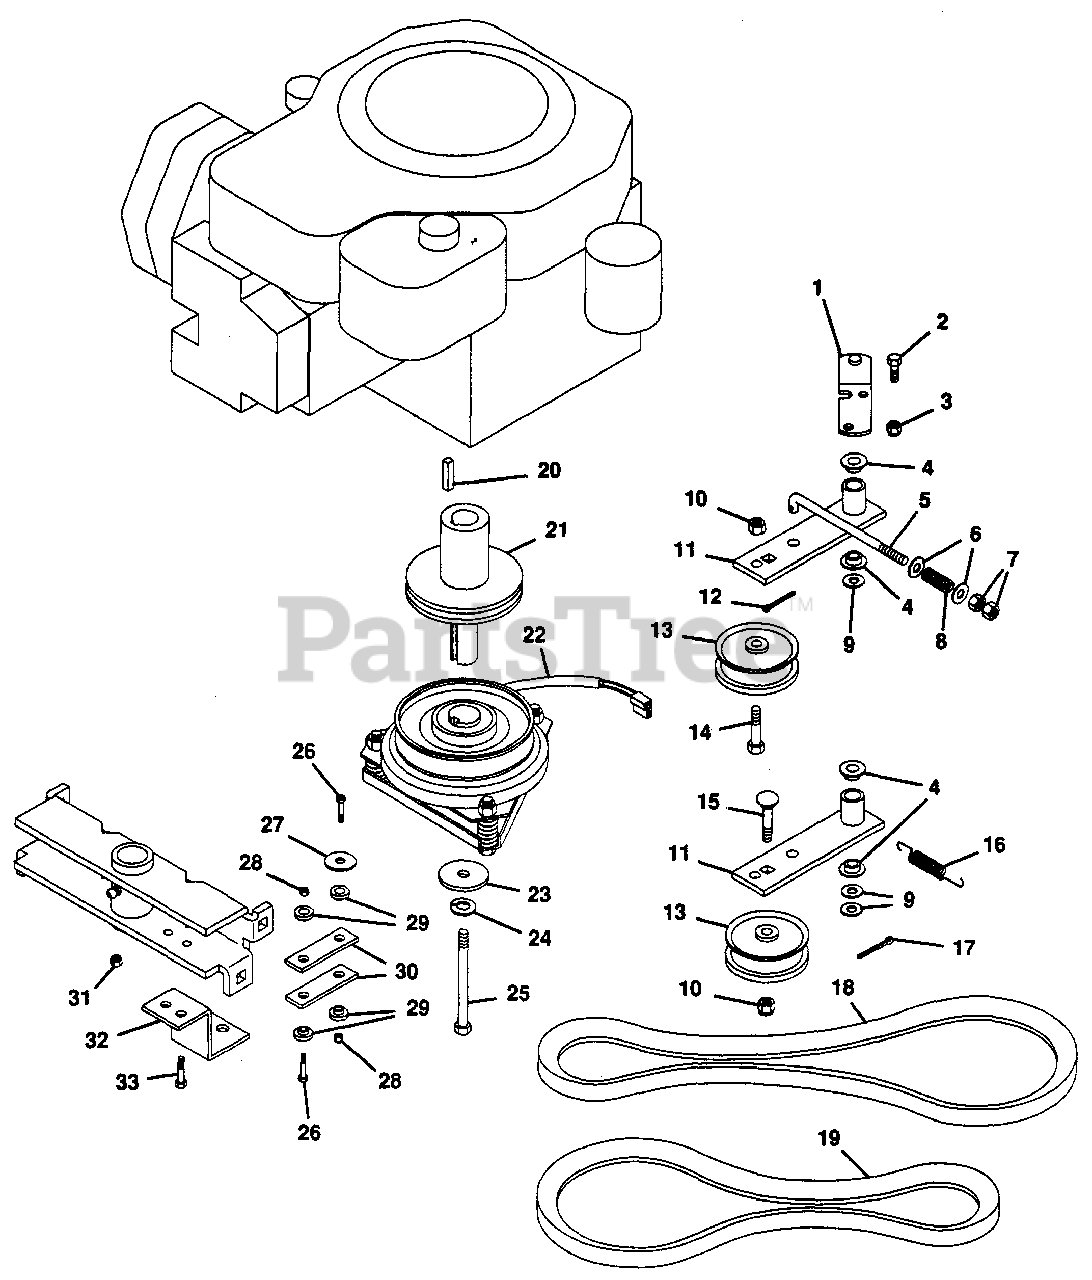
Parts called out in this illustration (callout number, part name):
1	Weldment, Idler Pivot
2	Bolt, Hex 5/16-18 x .75
3	Nut, Lock 5/16-18
4	Bushing, Flange
5	Rod, Idler
6	Washer, Flat .406 x .812 x .065
7	Nut, Hex 3/8-16
8	Spring, Comp. 1 x .78 x 338 Lb/In
9	Washer, Flat .531 x 1.000 x .063
10	Nut, Lock 3/8-16
11	Weldment, Idler
12	Pin, Cotter .094 x 1.00
13	Idler
14	Bolt, Hex 3/8-16 x 1.75
15	Bolt, 3/8-16 x 1.75 Rd Hd Sq Nk
16	Extension Spring
17	Pin, Cotter .125 x 1.25
18	Belt, Transaxle
19	V-Belt, Jackshaft
20	Key, Square .250 x 1.00
21	Weldment, Pulley
22	Clutch, Electric
23	Washer, Special
24	Washer, Lock 7/16 SP Heavy
25	Bolt, Hex M10-1.5 x 140 mm
25	Bolt, Hex 7/16-20 x 5.5 Gr. 5
26	Screw, Mach. 10-24 x 1.00 PHCR
27	Washer, Flat .265 x 1.250 x .063
28	Nut, Lock 10-24
29	Special Washer
30	Link
31	Nut, Lock 1/4-20
32	Bracket, Torque
33	Bolt, Hex 1/4-20 x .750
